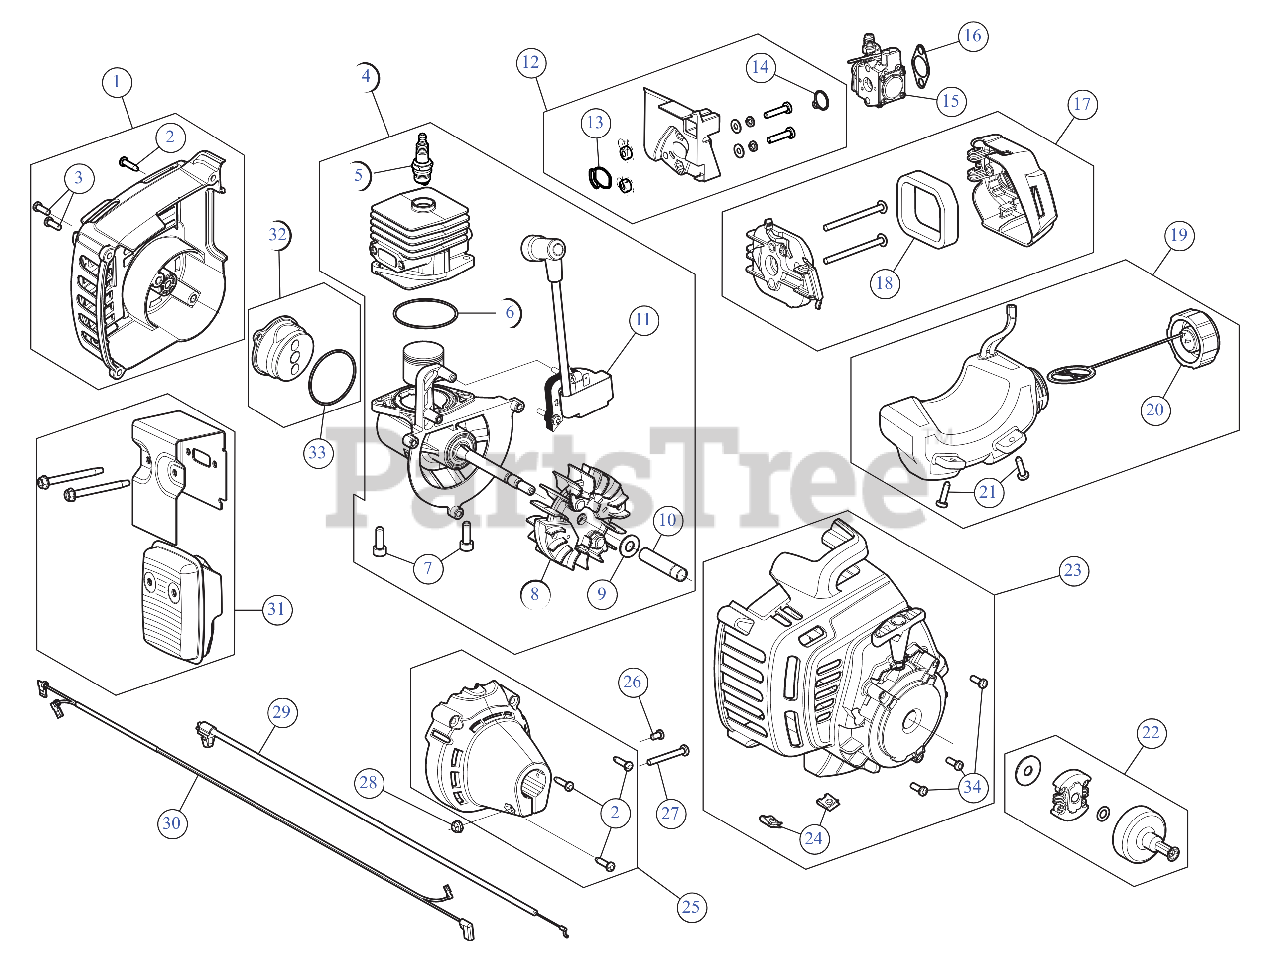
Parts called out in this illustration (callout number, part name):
1	REAR ENGINE COVER
2	SCREW, #8-16X.750 PH
3	SCREW #
4	SHORT BLOCK
5	SPARK PLUG
6	O-RING
7	SCREW, 1/4-20 x .75
8	FLYWHEEL ASSEMBLY
9	BELL WASHER
10	SPACER
11	MODULE 27CC DIG
12	INTAKE ASSEMBLY
13	O-RING
14	O-RING
15	CARBURETOR
16	GASKET CARB
17	AIR CLEANER ASSEMBLY
18	AIR FLITER
19	FUEL TANK ASSEMBLY
20	FUEL CAP ASSEMBLY
21	SCREW:10-6 x .75
22	SMALL CLUTCH ASSEMBLY W/SMALL DRUM
23	STARTER HOUSING ASSEMBLY
24	NUT, TINNERMAN U-T
25	CLUTCH COVER
26	SCREW, 8-32 x .312 P
27	SCREW
28	HEX NUT
29	THROTTLE CABLE
30	LEAD WIRES
31	MUFFLER ASSEMBLY
32	ELECTRIC START COVER
33	O-RING
34	SCREW:10-32X.562:#8P
